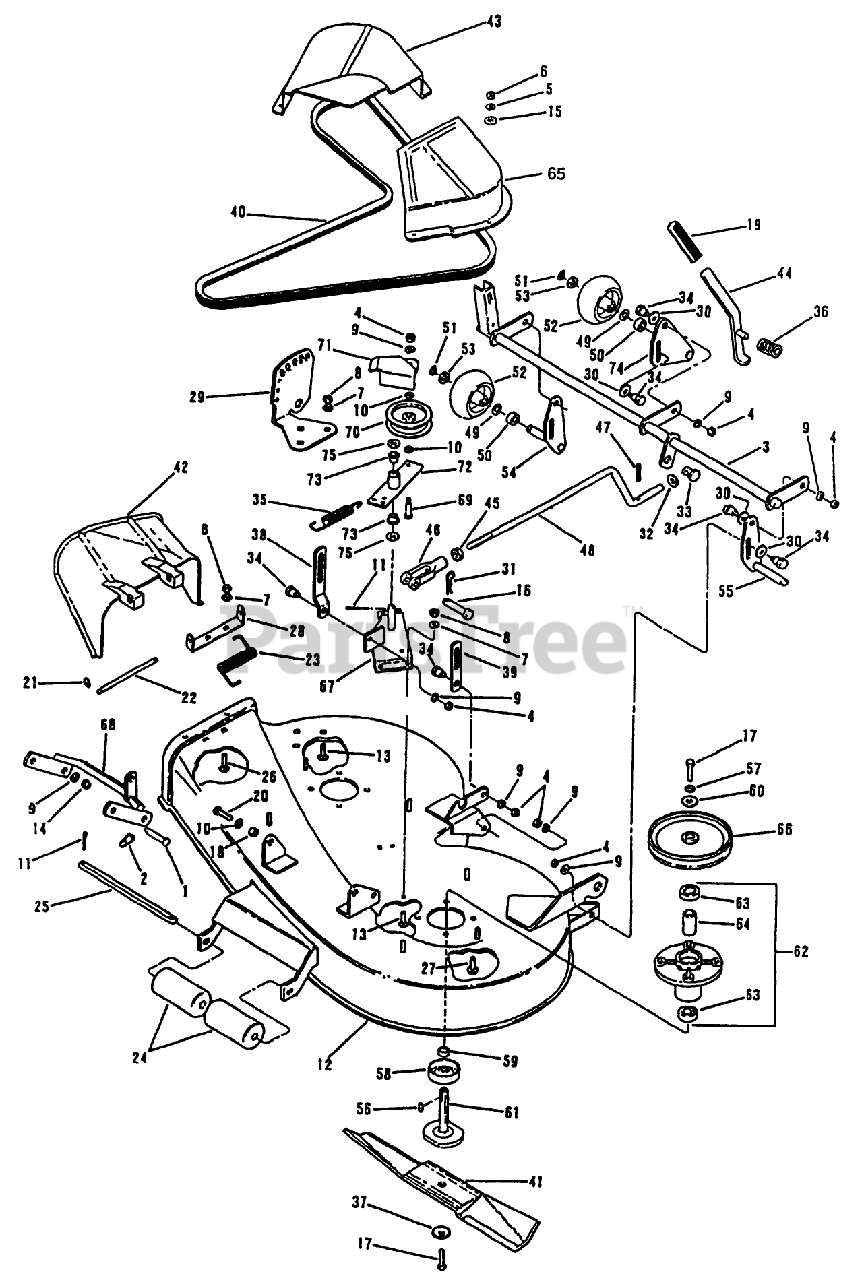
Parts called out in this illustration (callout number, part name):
1	PIN CLEVIS
4	NUT
6	NUT
8	NUT SS
9	WASHER
10	WASHER
13	BOLT - CARRIAGE
14	NUT-LOCKING
16	PIN CLEVIS
21	E-RING
22	SHAFT - CHUTE
24	ROLLER
25	SHAFT
27	SCREW-THD ROLL, HWH
31	PIN-HAIR
33	PIN - PIVOT
34	BOLT-SHOULDER
41	BLADE - LOW LIFT
43	COVER, BELT RH
46	CLEVIS
49	WASHER
51	RING
53	SPACER
58	SHIELD SPINDLE *B
59	SPACER
60	WASHER
62	HOUSING ASSEMBLY
65	COVER, BELT LH
68	HANGER ASSEMBLY *B
70	PULLEY - 4"
73	BUSHING
